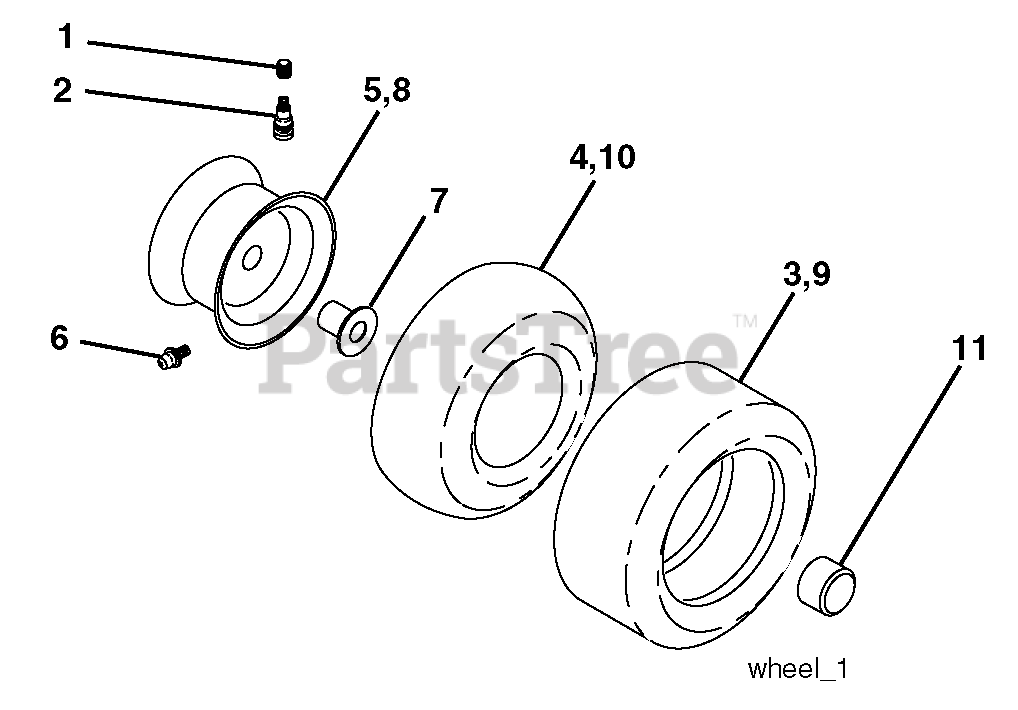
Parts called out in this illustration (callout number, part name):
1	Cap Valve Tire
2	Stem Valve
3	Tire F T 15 x 6 0 - 6
4	Tube Front
5	Rim Asm 6" Front
6	Fitting Grease
7	Bearing Flange
8	Rim Asm 8" Rear
9	Tire R T 18 x 9.5-8 Turf Saver
9	Tire R T 18 x 9.5-8 Turf Saver LT
10	Tube Rear
11	Cap Axle Blk 1 50 x 1 00
11	Sealant, Tire (10 oz. Tube)
